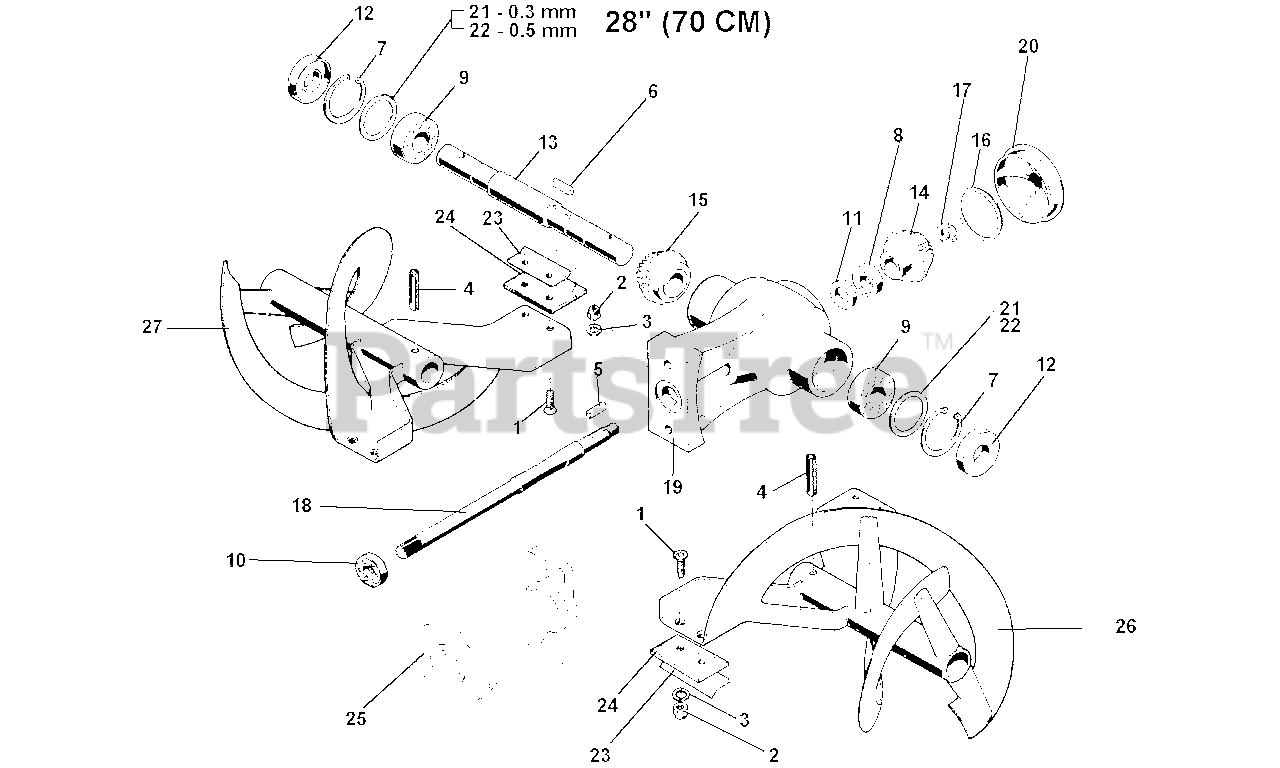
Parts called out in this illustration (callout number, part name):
1	SCREW M6 X 25
2	NUT, SELF LOCKING M6
3	WASHER, FLAT 6.4
4	PIN, LOCKING 10 X 50 DIN 1481
5	FLAT KEY 6 X 6 X 25 ACC.
6	FLAT KEY 10 X 30 X 8 ACC.
7	CIRCLIP, INTERN D 62
8	BEARING 20 X 47 X 14 6204
9	BEARING 30 X 62 X 16 6206
10	BEARING 20 X 47 X 14 6204 2RS ST
11	OIL SEAL 25 X 40 X 7
12	SEAL, OIL 30 X 62 X 10 STANDARD
13	ROTARY HOE SHAFT
14	ROTARY HOE BEVEL GEAR
16	RUBBER GASKET
17	RING SELF-BLOCK
18	P.T.O. SHAFT
19	CENTRAL CASING OF SNOW THROWER
20	CENTRAL CASING CAP
21	SHIM 0.3 MM
22	SHIM 0.5 MM
24	RUBBER FLAP
25	P.T.O. COUPLING
26	RIGHT ROTARY HOE
27	LEFT ROTARY HOE
